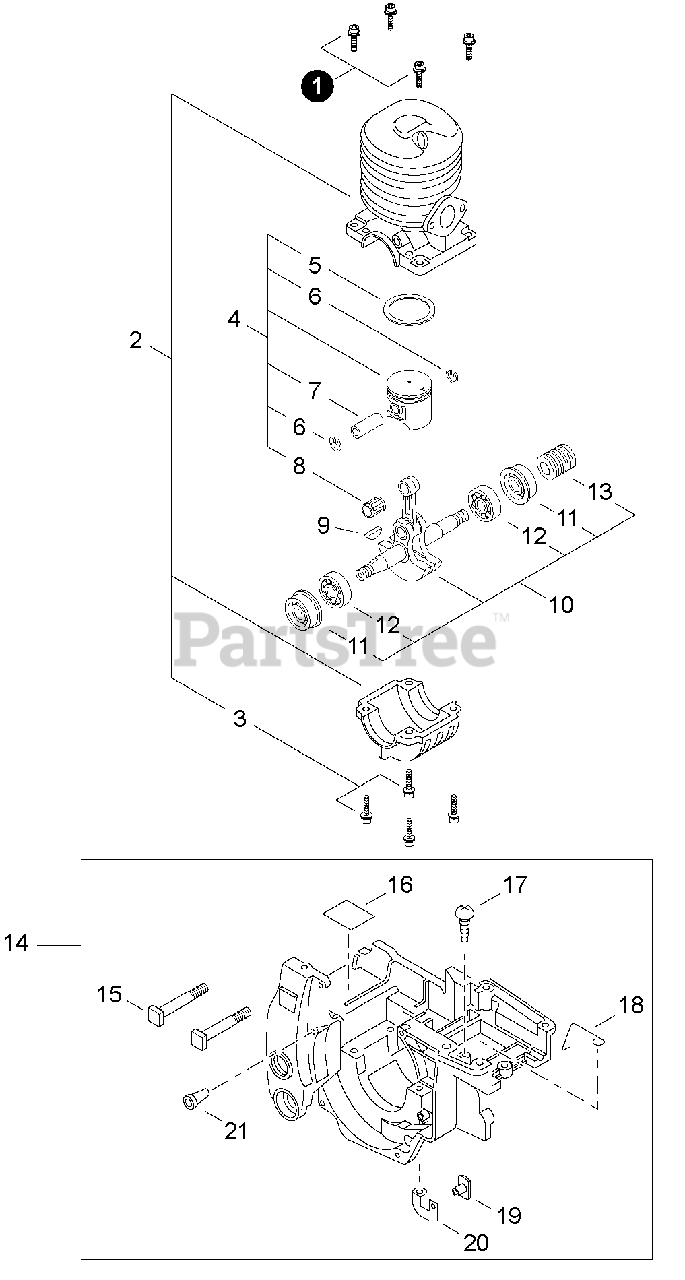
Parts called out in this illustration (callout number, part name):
1	SCREW - 5X30
2	CRANKCASE KIT
3	SCREW - 5X22
4	PISTON KIT
5	RING, PISTON
6	RING, RETAINING
7	PIN, PISTON
8	BEARING, NEEDLE
10	CRANKSHAFT ASSY
11	SEAL, OIL - 12
12	BEARING, BALL - 6201
13	GEAR - WORM
14	ENGINE COVER ASSY
15	STUD, GUIDE BAR
16	DEFLECTOR, HEAT
17	SCREW - 4X8
18	WIRE
20	PLATE - GROUND
21	VENT, TANK
